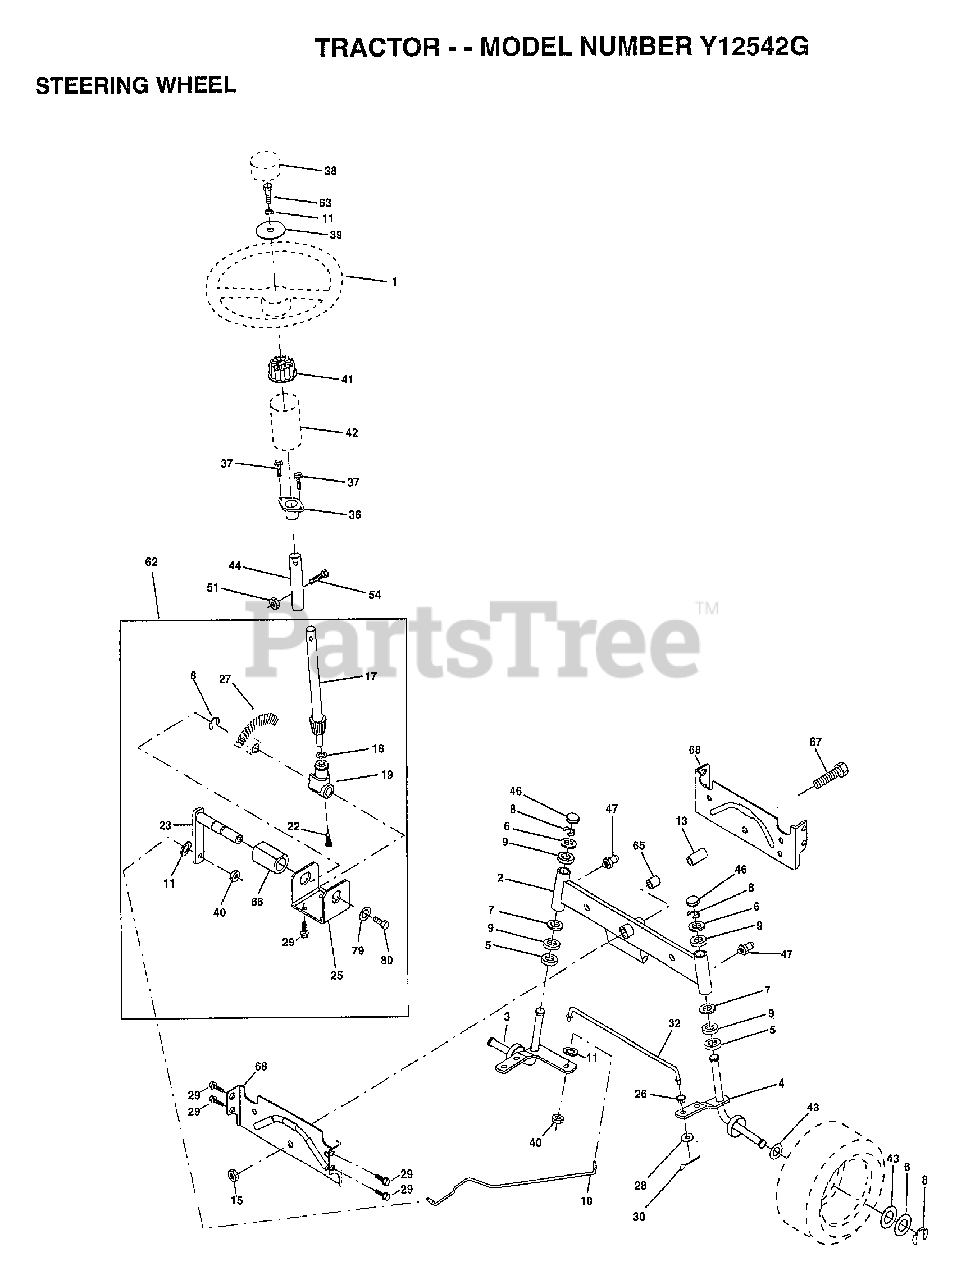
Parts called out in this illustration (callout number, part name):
1	WHEEL STR AYP BLK
2	AXLE ASM
3	SPINDLE.ASM.LH
4	"SPINDLE ASM,RH"
5	WASHER .T
6	WASHER
7	WASHER
8	RING
9	COL. SRTG. BEAR.
10	DRAGLINK-STAMPED
11	LOCKWASHER
13	BEARING AXLE
15	"NUT-LOC,FLANGE LT"
17	SHAFT ASM STEERIN
18	THRUST WASHER
19	SUPPORT.SHAFT.STEER
22	SCREW.HX.WSH.HD
23	SHAFT.ASM.PITMAN
25	BRKT-STEERING
26	BUSHING.DRAGLINK
27	GEAR SECTOR
28	WASHER
29	SCREW
30	COTTER PIN
32	TIE ROD
36	BUSHING.STEERING
37	"SCREW-TT,10-32 FL"
38	CAP STEER AYP
39	WASHER T
40	GRIPCO NUT
41	ADAPTER LT
42	BOOT.STEER.PL
43	WASHER
44	EXT SHAFT STEERIN
46	CAP
47	ZERK M
51	NUT
54	BOLT
62	KIT.STEER.ASM
63	BOLT
65	SPACER AXLE
66	"BEARING-ARM,PITMA"
67	BOLT
68	BRACE AXLE
79	WASHER
80	BOLT.HX.NYLON3/8-16X3/
